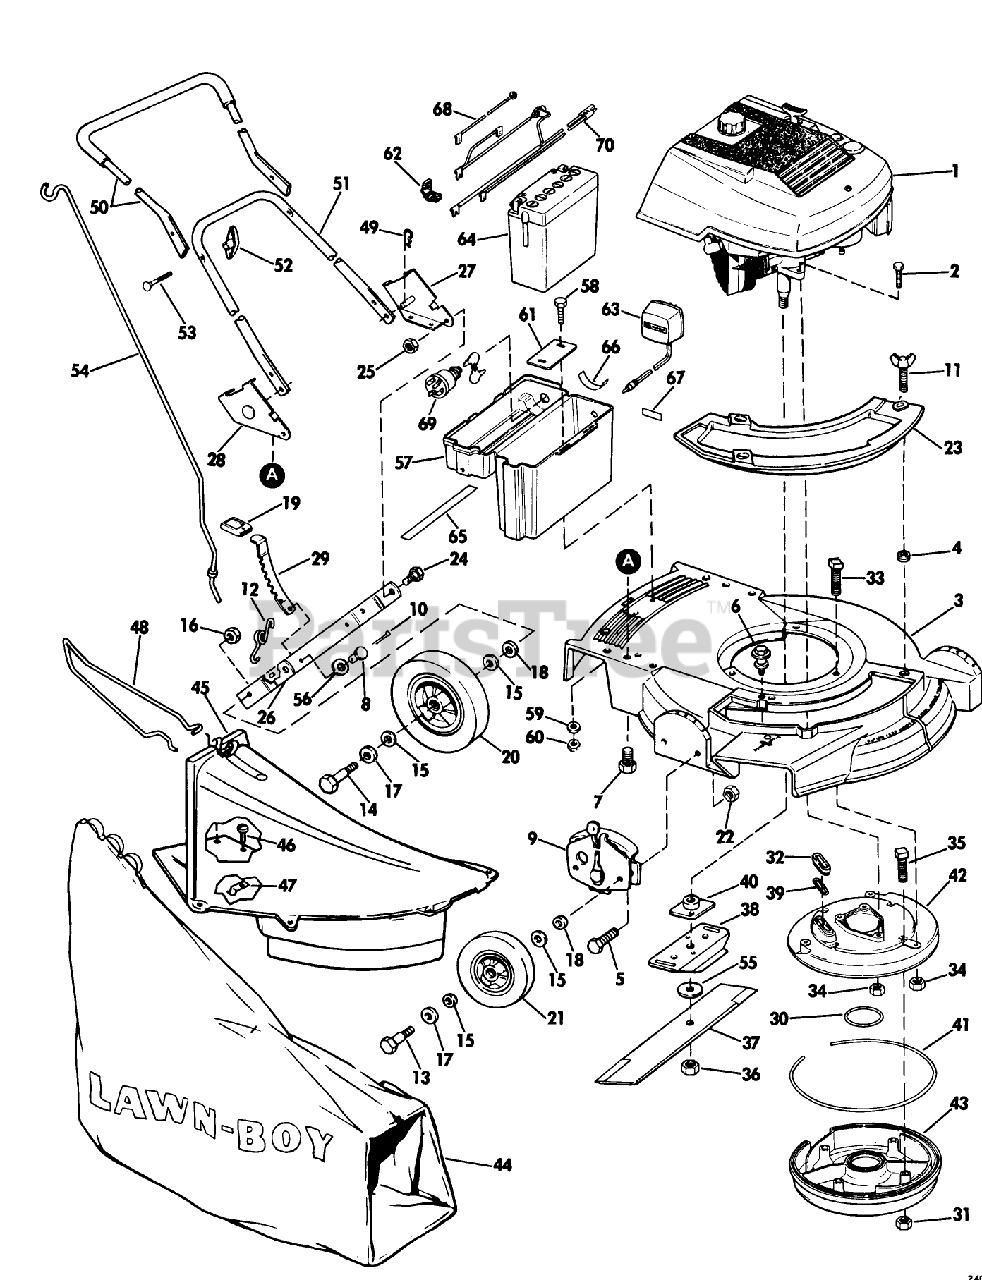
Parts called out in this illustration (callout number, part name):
2	BOLT F
7	SCREW
8	PIN
11	WING SCREW LAWRE
12	SPRING N.A.S
13	BOLT WHEEL
14	BOLT
15	WASHER
16	LOCKNUT
17	SPACER
18	WASHER WROUGHT
19	KNOB
22	NUT
24	BOLT-SHOULDER
25	NUT
31	LOCKNUT E
32	SLEEVE
33	SCREW V
34	NUT
35	SCREW
36	NUT-BLADE
39	GASKET S
40	PLATE AND COLLAR ASM
41	Gasket Muffler (outside)
49	HAIR PIN
52	NUT-WING
54	ROD GRASSBAG
55	WASHER
56	WASHER SPRING LAR
59	WASHER
63	BATTERY CHARGER
64	Battery
67	Decal, Charge
